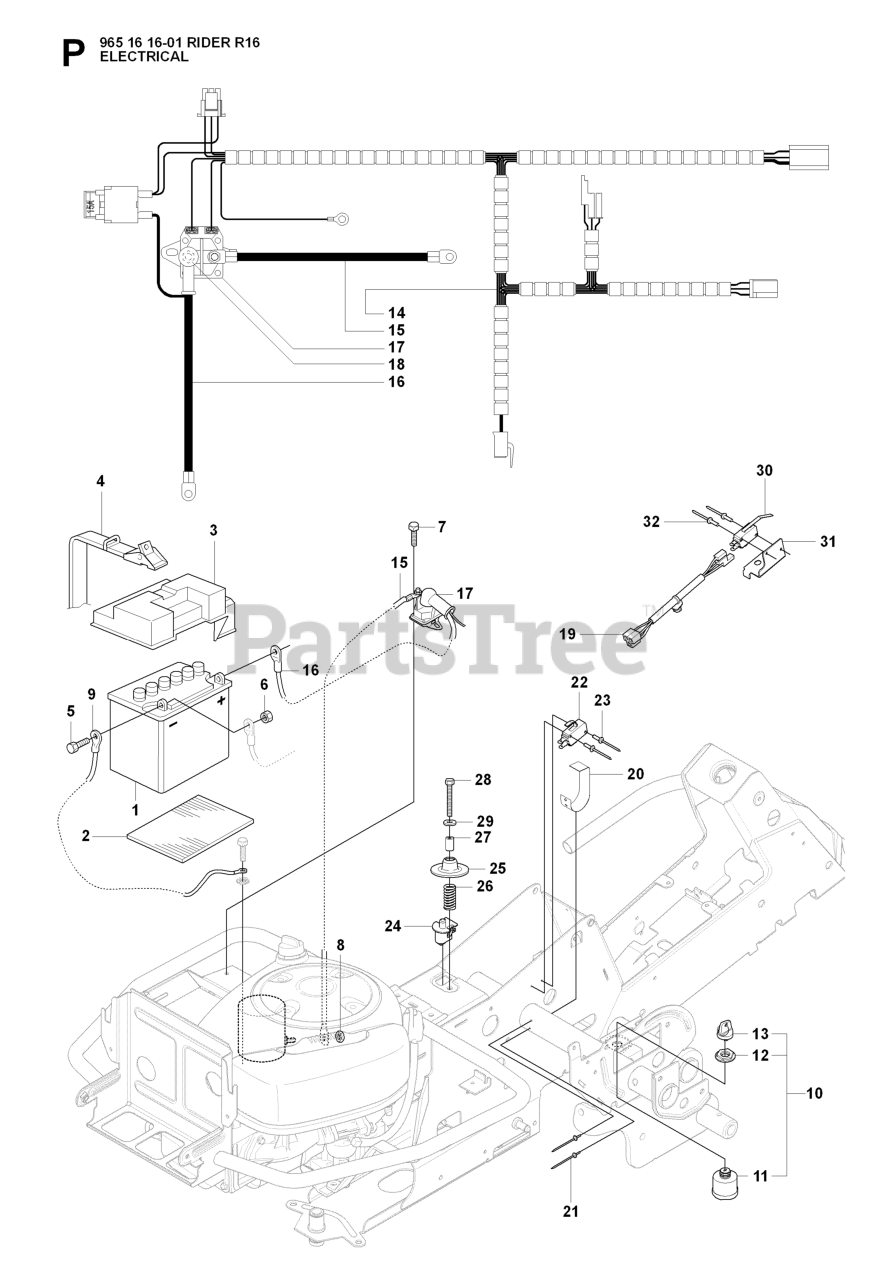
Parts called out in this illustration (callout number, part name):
1	BATTERY - DRY
10	IGNITION SWITCH
11	IGNITION SWITCH
13	IGNITION KEY
19	WIRING
22	%BRAKER
27	SPACER TUBE
28	SCREW
29	WASHER BRB 8.4X17
30	RP MICRO SWITCH
